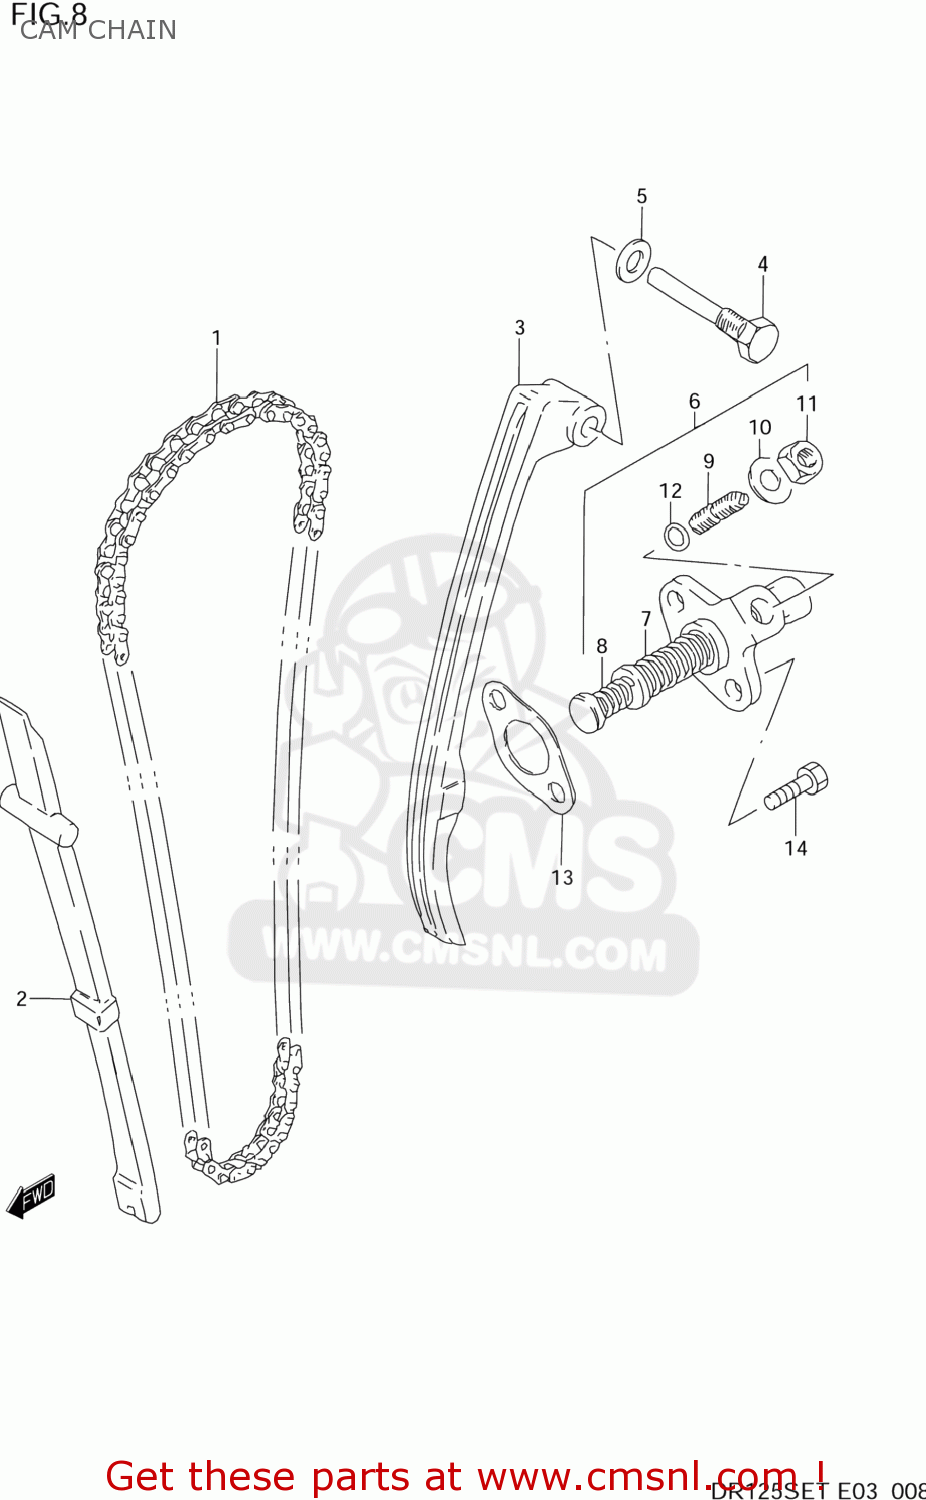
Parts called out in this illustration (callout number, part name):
1	CHAIN,CAMSHAFT DRIVE
2	GUIDE,CAM CHAIN
3	TENSIONER,CAM CHAIN
4	BOLT,CAM CHAIN TENSIONER
5	GASKET 8.2X14X1 (NAS)
6	ADJUSTER ASSEMBLY,TENSIONER
7	SPRING
8	SPRING
9	SCREW
10	WASHER
11	NUT
12	O RING(D:1.9,ID:5.7)
13	GASKET,TENSIONER ADJUSTER (NAS)
14	BOLT
